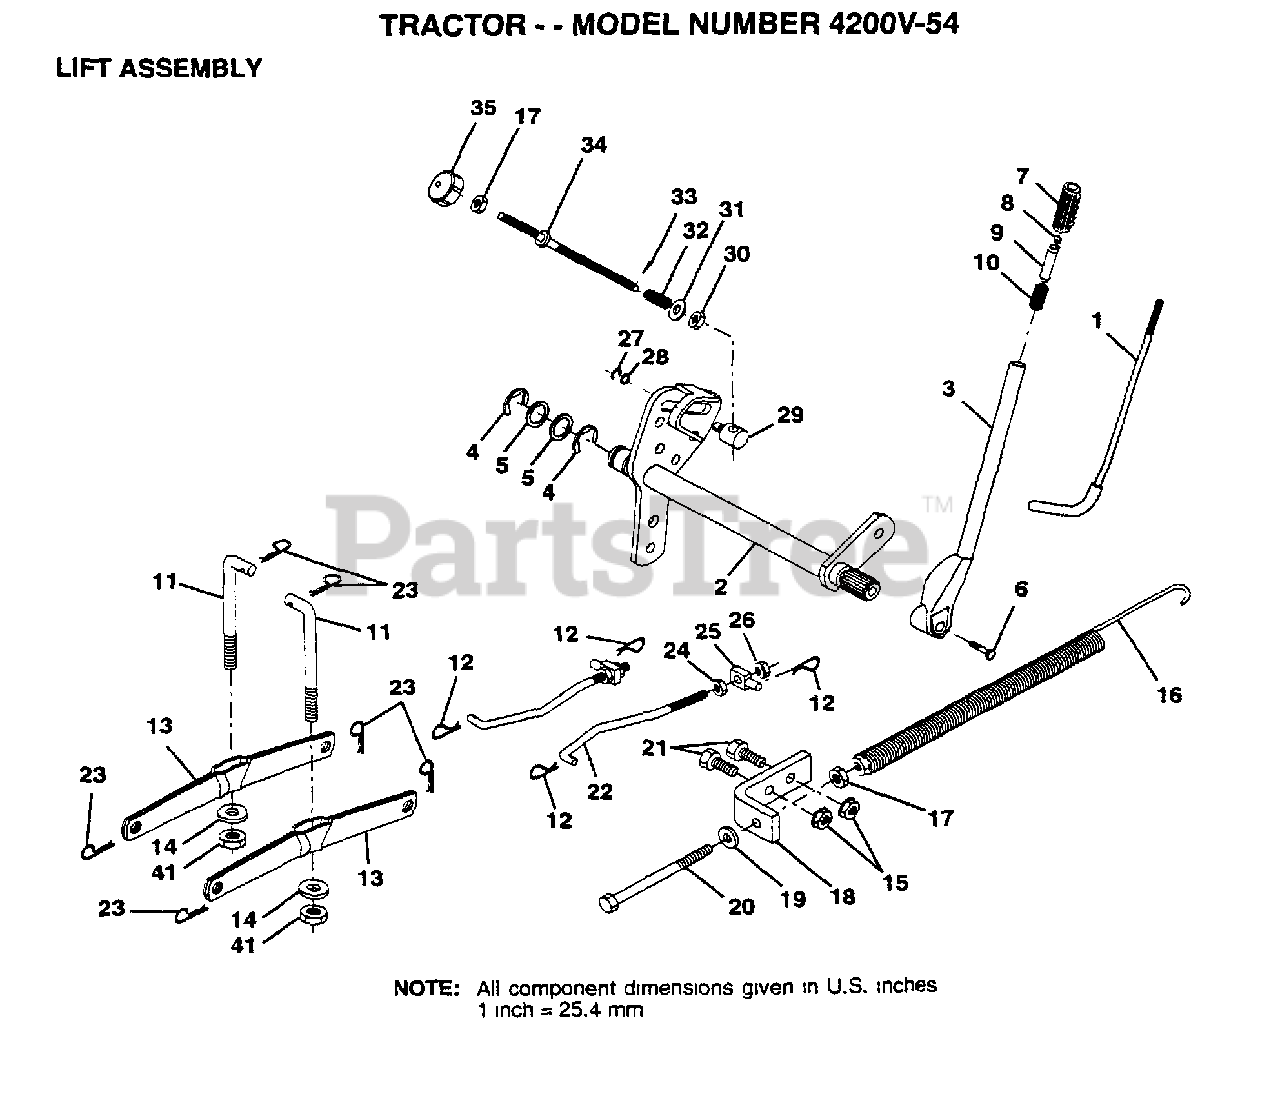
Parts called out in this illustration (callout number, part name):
1	LEVER ROD LT
4	E-RING
5	WASHER
6	"BOLT,HEX"
7	GRIP
10	SPRING T
12	RETAINER.SPRING
14	BEARING PVT LH
17	NUT
18	BRACKET SPRING AS
19	WASHER
20	BOLT-ADJ SPRING T
21	BOLT
22	LINK.FRONT
24	NUT
25	TRUNION
26	NUT.LK.W/WSH.1/2.
27	KLIP RING
28	WASHER
29	TRUNION LT
30	NUT T
31	WASHER
32	SPRING.COMP.INF.H
34	ROD.ADJ.LIFT
35	KNOB INF 3/8-16
41	NUT.CROWNLOCK.3/8
